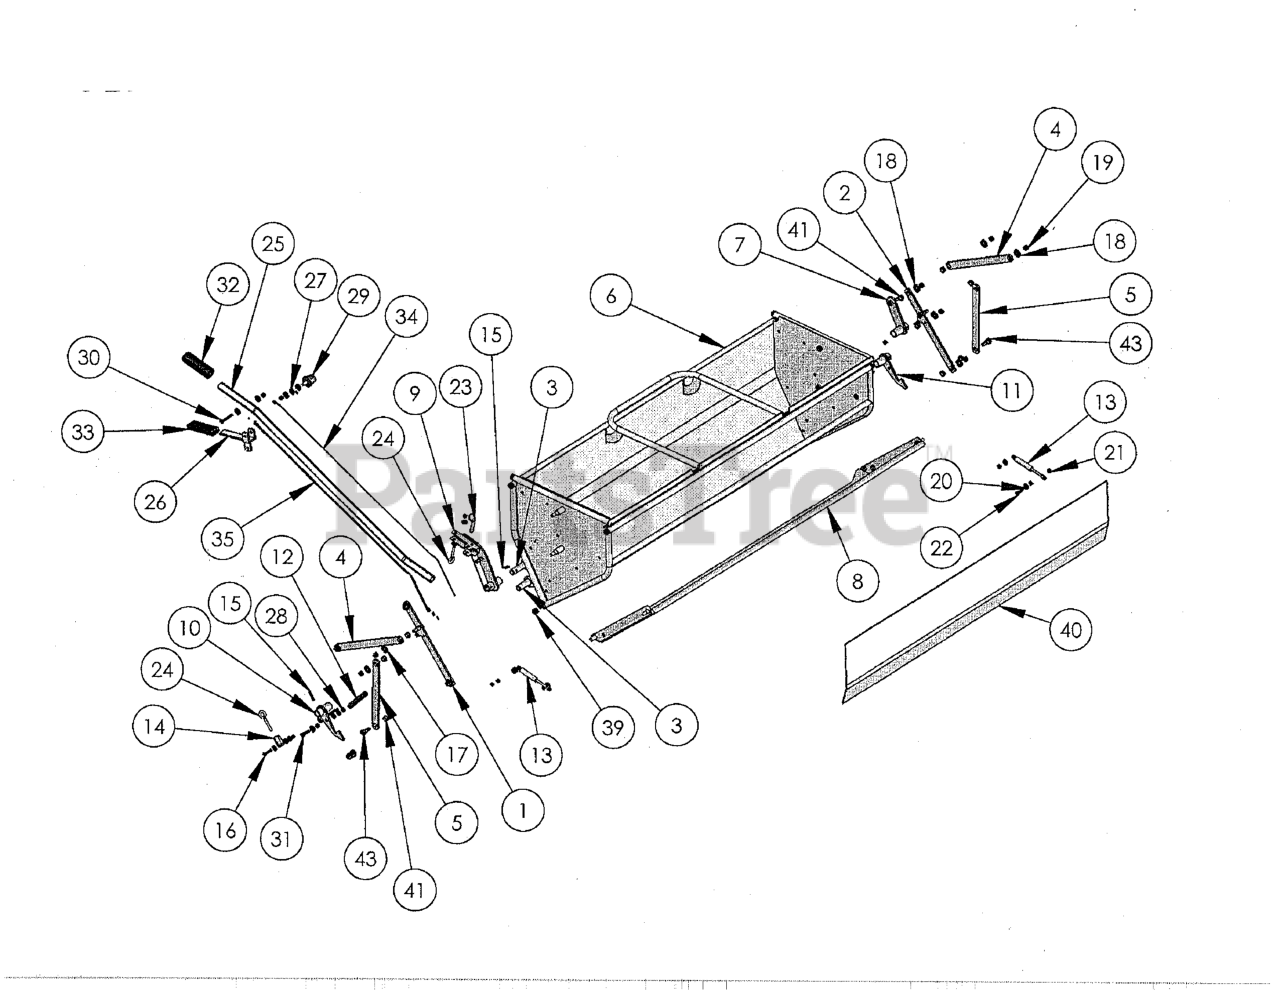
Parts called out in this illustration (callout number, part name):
1	MASTER LINK, LH
2	MASTER LINK, RH
7	TORQUE LINK ASSEMBLY
9	HANDLE PIVOT
10	LATCH ASSEMBLY, LH
11	LATCH ASSEMBLY, RH
12	TENSION SPRING
14	CABLE ADJUST. BLOCK
26	DFS WELD LEVER
29	RUBBER STOPPER
33	RUBBER GRIP
34	1/16 CABLE
37	1/16 CABLE TIE
41	FLANGE BUSHING
43	SHOULDER BOLT
